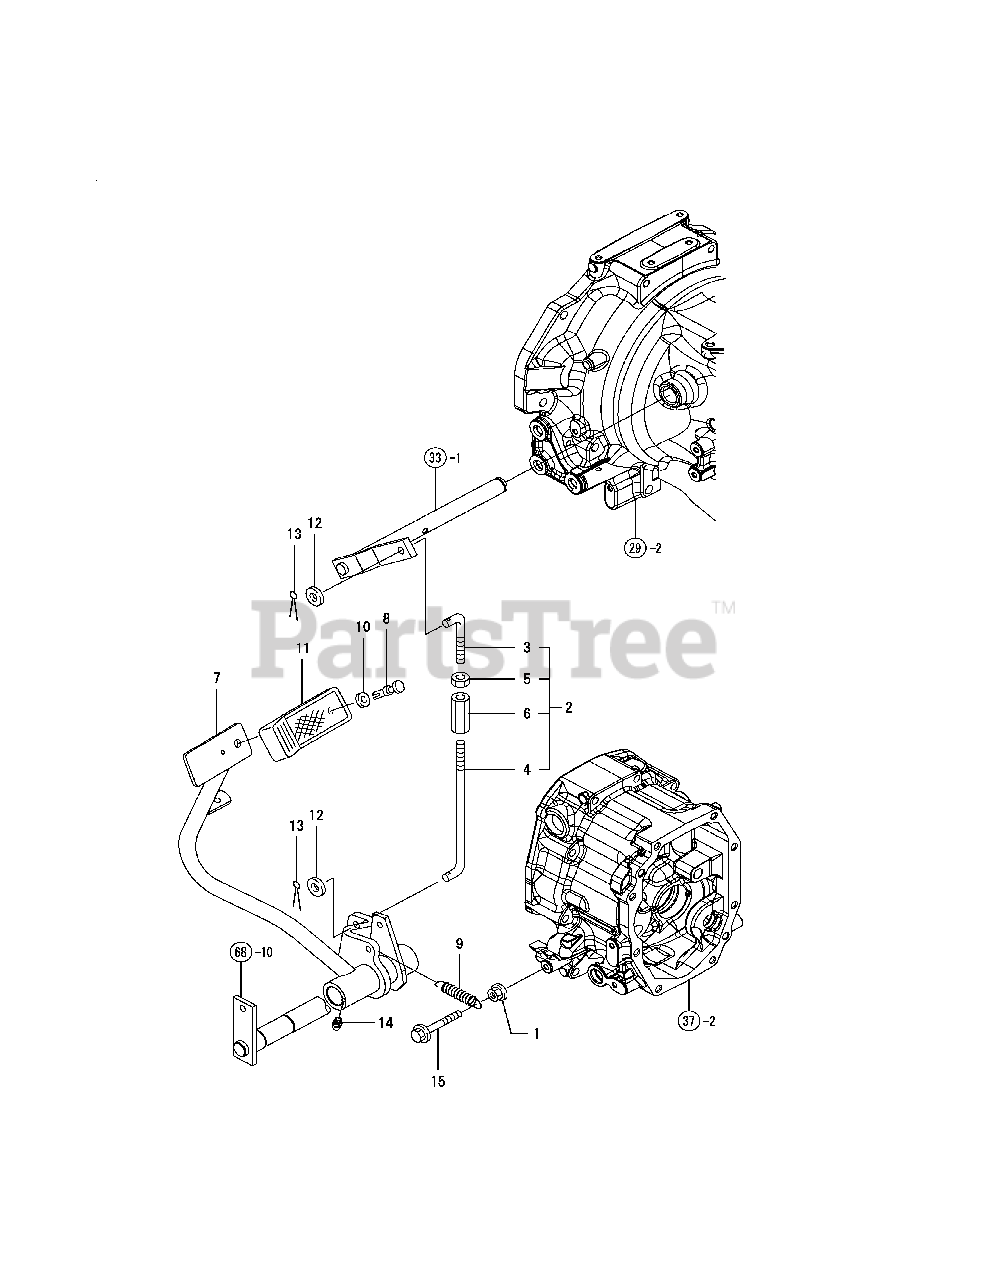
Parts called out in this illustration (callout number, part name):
1	NUT W/WASHER 8
2	ROD KIT, CLUTCH PEDAL
6	TURNBUCKLE M10
8	RIVET, PEDAL HEAD
9	SPRING, CLUTCH
11	COVER, PEDAL HEAD
12	WASHER 10,POLISHED
13	COTTER PIN 2.5X30
14	NIPPLE M6F, GREASE
15	BOLT M 8X 50 PLATED
